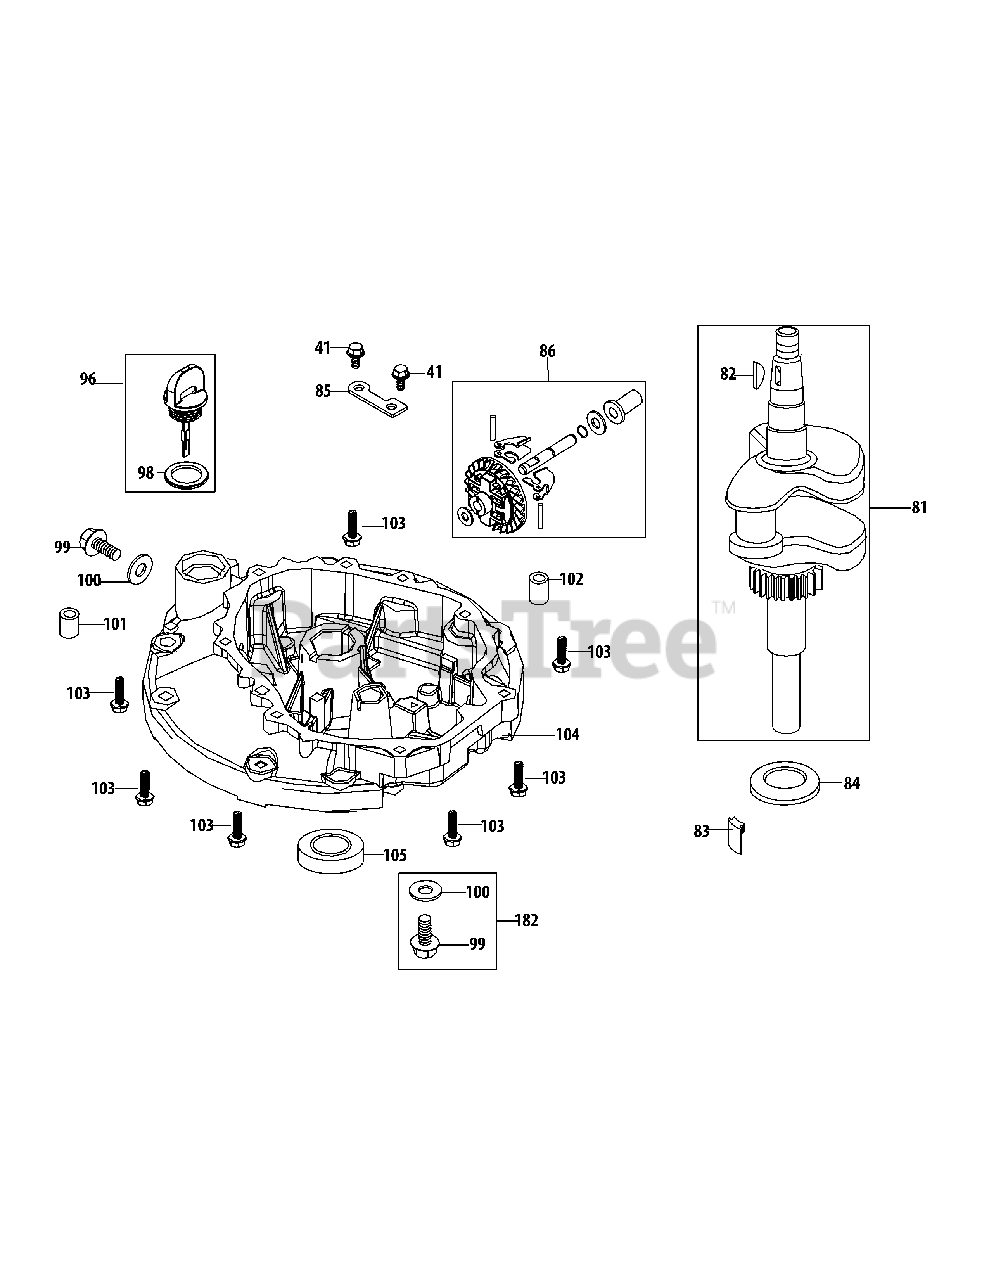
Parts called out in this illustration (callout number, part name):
41	Bolt M6X14
81	Crankshaft Assembly
82	Woodruff Key
83	Oil Return Seal
84	Crankshaft Thrust Washer
85	Governor Gear Mounting Plate
86	Governor Gear/Shaft Assembly
96	Dipstick Assembly
98	Dipstick O-Ring
99	Oil Drain Plug
100	Oil Drain Plug Washer
101	Crankcase Cover Dowel Pin 9×14
102	Crankcase Cover Dowel Pin 7×14
103	Bolt M6X28 P65 Crankcase
104	Crankcase Cover
105	Lower Crankshaft Seal
182	Oil Drain Plug & Washer Asm
